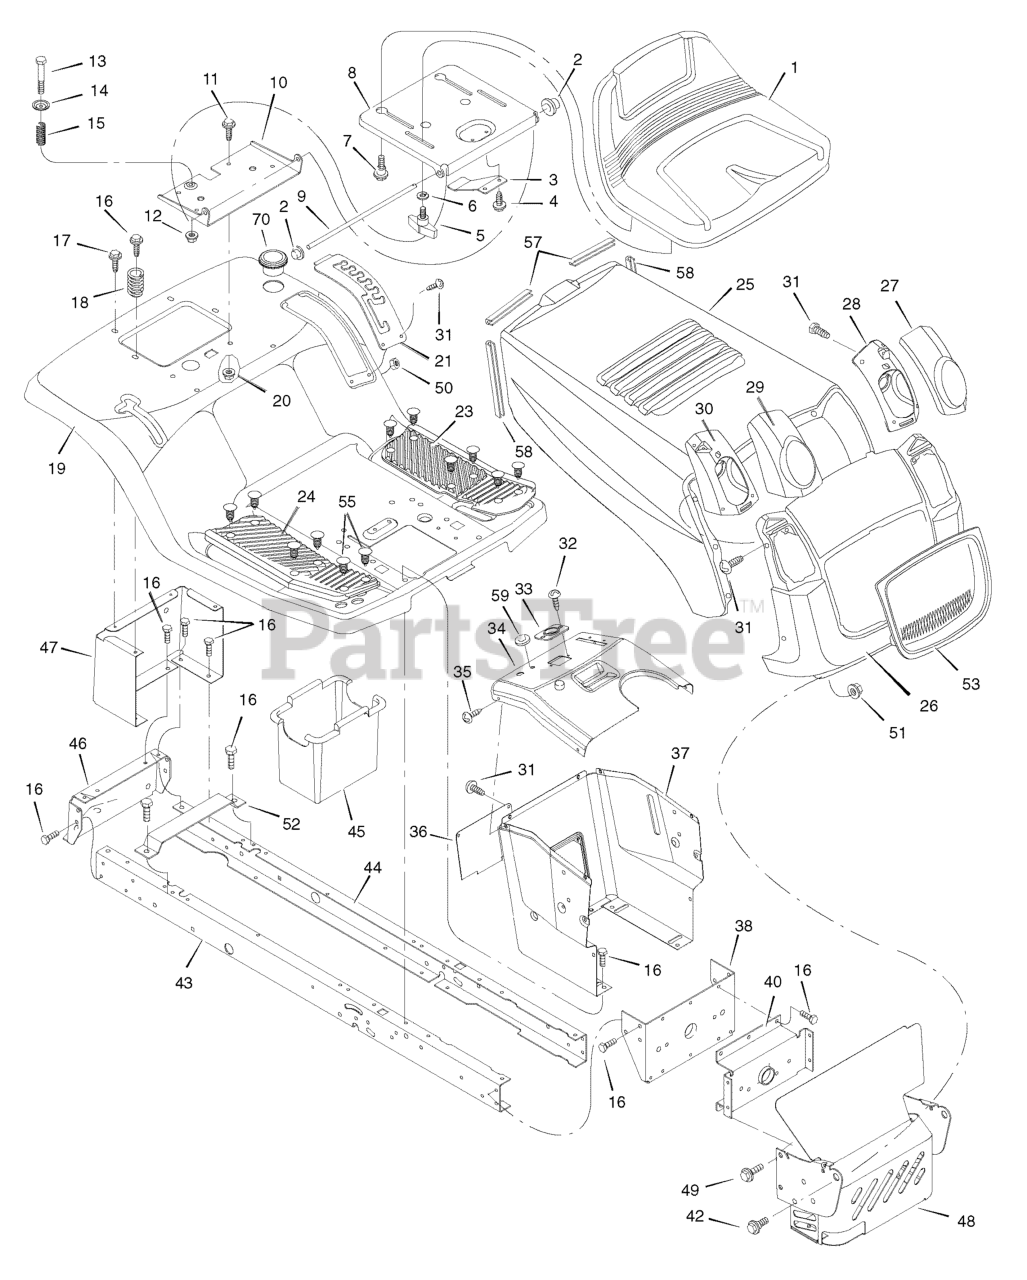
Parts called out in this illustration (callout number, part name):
1	Seat
2	Cap, Push 0n
5	Bolt, Wing
6	Washer
7	Bolt, Shoulder
8	Support, Seat
9	Rod, Pivot
10	Bracket, Pivot
11	Bolt
13	Bolt, Shoulder
20	Nut
21	Plate, Index Detent
23	Mat, Left
24	Mat, Right
26	Grille
27	Lens, Left
28	Housing, Left Headlamp
29	Lens, Right
30	Housing, Right Headlamp
33	Bearing, Steering
34	Dash
36	Panel, Access
37	Support, Dash
38	Bracket, Rear Hanger
40	Axle, Hanger
42	Bolt
43	Frame, Right
44	Frame, Left
45	Container, Battery
46	Plate, Hitch
47	Panel, Rear
48	Shield, Heat
51	Nut
52	Support, Battery
53	Insert, Grille
55	Fastener, Panel
57	Trim, Hood (3.75")
58	Trim, Hood (6.5")
59	Grommet, Parking Brake
60	Assembly, Headlamp R.H.
61	Assembly, Headlamp L.H.
70	Holder, Cup
